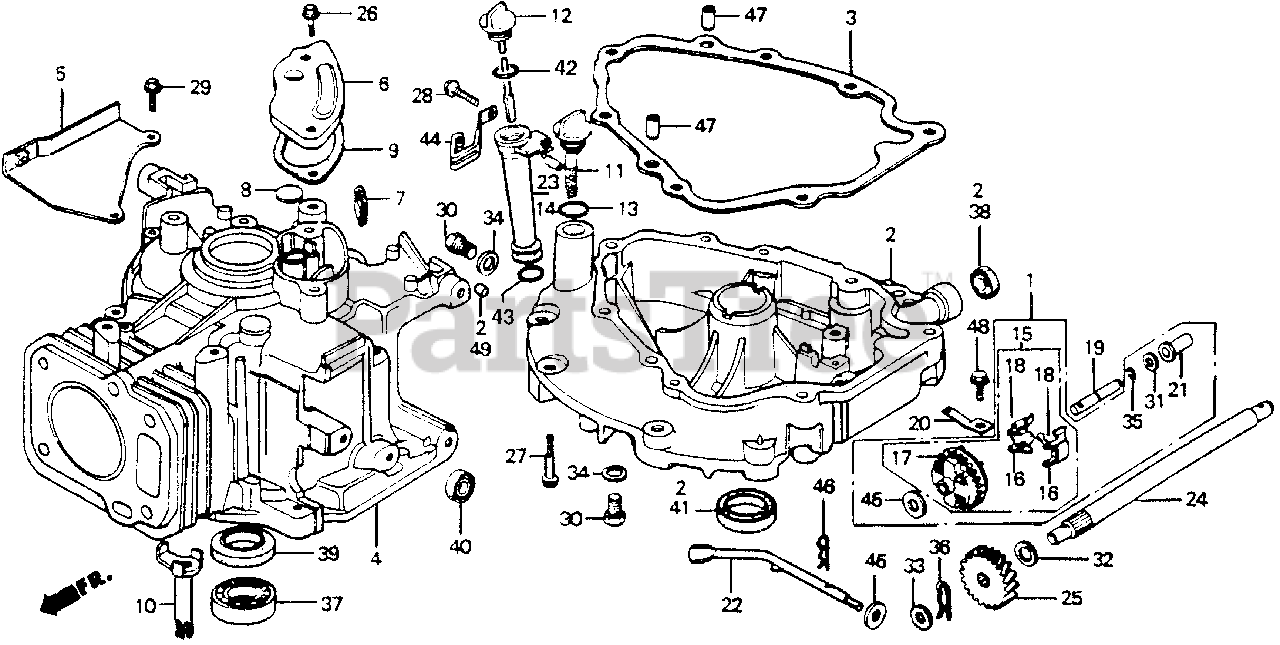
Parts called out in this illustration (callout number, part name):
1	GOVERNOR KIT
2	PAN ASSY., OIL
2	PAN, OIL
3	GASKET, OIL PAN
3	GASKET, OIL PAN (HPE)
4	CYLINDER
5	PLATE, GUIDE
6	CAP, BREATHER CHAMBER
7	FILTER, BREATHER
8	VALVE, BREATHER
9	GASKET, BREATHER CHAMBER
10	PIPE, OIL DEFENSE
11	CAP, OIL FILLER (NOT AVAILABLE)
11	CAP, OIL FILLER
12	DIPSTICK, OIL Use up to Engine SN 1257294.
12	DIPSTICK, OIL
13	GASKET, OIL FILLER CAP
14	EXTENSION, OIL FILLER (106MM)
14	EXTENSION (90MM) (NOT AVAILABLE) Use up to Engine SN 1257294.
14	EXTENSION (90MM) (NOT AVAILABLE)
15	GOVERNOR ASSY.
16	WEIGHT, GOVERNOR
17	HOLDER, GOVERNOR WEIGHT
18	PIN, GOVERNOR WEIGHT
19	SHAFT, GOVERNOR HOLDER
20	PLATE, GOVERNOR SHAFT HOLDER
21	SLIDER, GOVERNOR
22	SHAFT, GOVERNOR ARM (NOT AVAILABLE)
22	SHAFT, GOVERNOR ARM
23	COLLAR, EXTENSION Use up to Engine SN 1257294.
23	COLLAR, EXTENSION
26	BOLT, FLANGE (6X12) (CT200)
27	BOLT, FLANGE (6X28)
28	BOLT, FLANGE (6X32) Use up to Engine SN 1257294.
28	BOLT, FLANGE (6X32)
29	BOLT, FLANGE (6X20) (CT200)
30	BOLT, DRAIN PLUG
31	WASHER, THRUST (6MM)
34	WASHER, DRAIN PLUG (10.2MM)
35	CLIP, GOVERNOR HOLDER
37	BEARING, RADIAL BALL (62/22)
39	OIL SEAL (22X35X6)
40	OIL SEAL (6X11X4)
41	OIL SEAL (25X38X7)
41	OIL SEAL (25X38X7) (ARAI)
42	O-RING (26X2.7) Use up to Engine SN 1257294.
42	O-RING (26X2.7)
43	O-RING (22.5X2.2)
43	O-RING (22.1X2) Use up to Engine SN 1257294.
45	WASHER, PLAIN (6MM)
46	PIN, LOCK (8MM)
47	PIN A, DOWEL (8X14)
48	BOLT, FLANGE (6X12)
49	PLUG, CONE TYPE (12X12)
